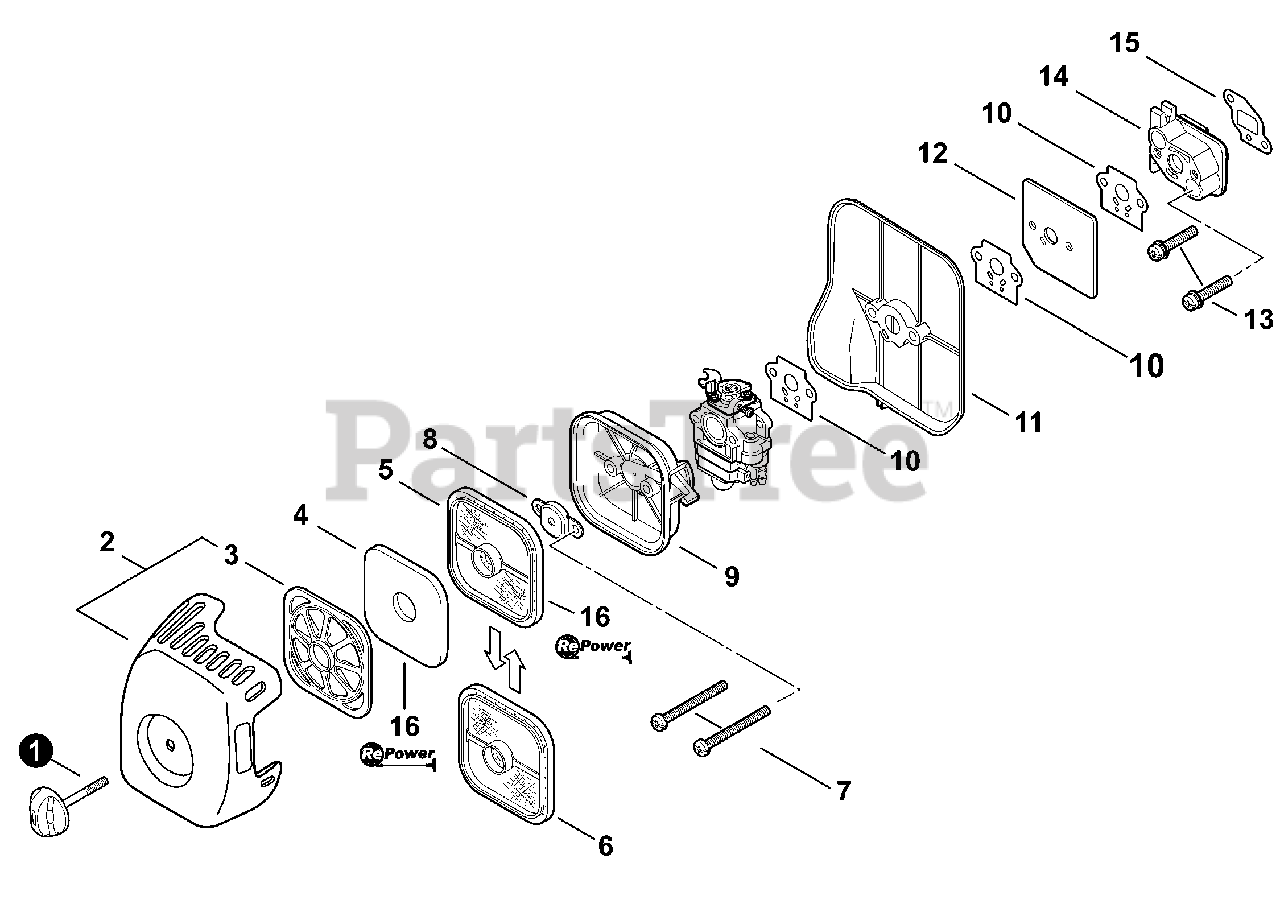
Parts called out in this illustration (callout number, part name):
1	THUMBSCREW
2	COVER KIT, AIR FILTER
3	RETAINER, PRE-FILTER
4	PRE-FILTER, FOAM
5	FILTER, AIR - DOUBLE LAYER
6	FILTER, AIR - SINGLE LAYER
7	SCREW 5×70
8	PLATE, PREVENT
9	CASE, AIR FILTER
10	GASKET, INTAKE
11	PLATE, INSULATOR
12	PLATE, INSULATOR
13	BOLT 5×30
14	INSULATOR, INTAKE
15	GASKET, INTAKE
16	TUNE-UP KIT - REPOWER
